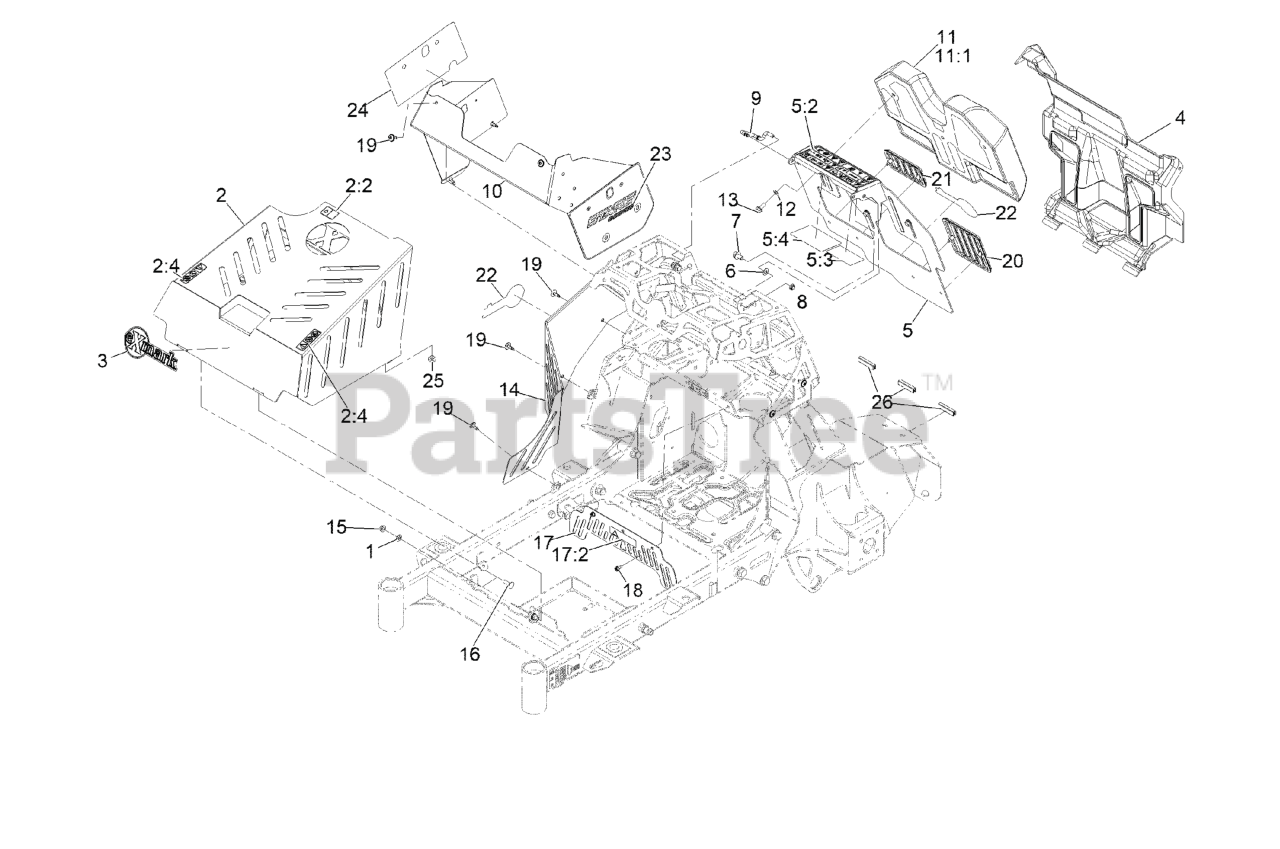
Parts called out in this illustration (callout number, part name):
1	SPACER-NYLON
2	ASM-COVER W DECALS
2:2	DECAL-WARNING
2:4	DECAL-NO STEP/RIDERS
3	DECAL, EXMARK LOGO
4	COVER-REAR STE
5	ASM, PAD BACKING W/ DECALS
5:2	DECAL-WARNING
5:3	DECAL-DRIVE RELEASE
5:4	DECAL-SERVICE AID SM
6	WASHER-THRUST
7	SCREW-HHF
9	ROD, PROP
10	SKIN, TOWER
11	PAD-THIGH
11:1	COVER, PAD
12	WASHER-BELLEVILLE
13	SCREW-HHF
14	COVER, RT SIDE
16	BOLT-CARR
17	ASM, BELT GUARD W/ DECAL
17:2	DECAL-WARNING
18	SCREW-HWH
19	SCREW, TORX
20	PAD, KNEE, LT
21	PAD, KNEE, RT
22	DECAL-EXMARK LOGO
23	DECAL-STARIS LOGO LT
24	Decal-Staris Logo Rt
26	STRIP-SEAL 2.13
